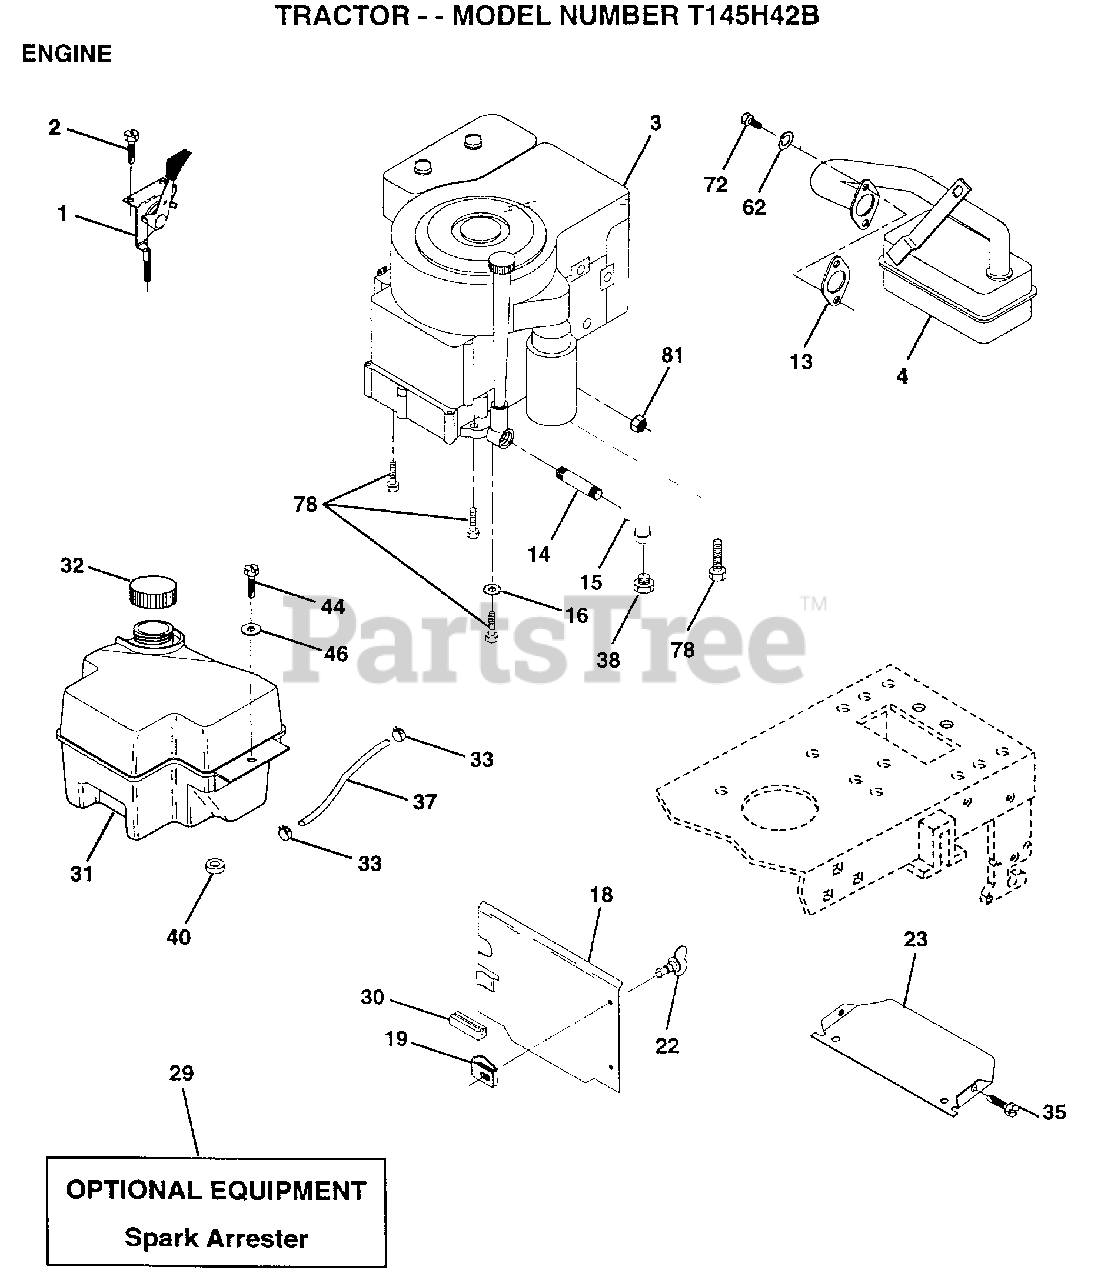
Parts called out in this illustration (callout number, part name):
1	CONTROL THROTTLE
2	SCREW LT
4	MUFFLER
13	GASKET ENG 1 313 LD TIN PLATED
14	PIPE NIPPLE
15	ELBOW
16	LOCKWASHER
18	SHIELD HEAT
19	RECEPTACLE LT
22	"STUD 1/4 TURN,BUS"
32	CAP ASM FUEL
33	HOSE CLAMP
35	SCREW
37	LINE FUEL
44	SCREW HEX CRT
46	WASHER
62	LOCKWASHER
72	SCREW
78	SCREW
81	NUT
